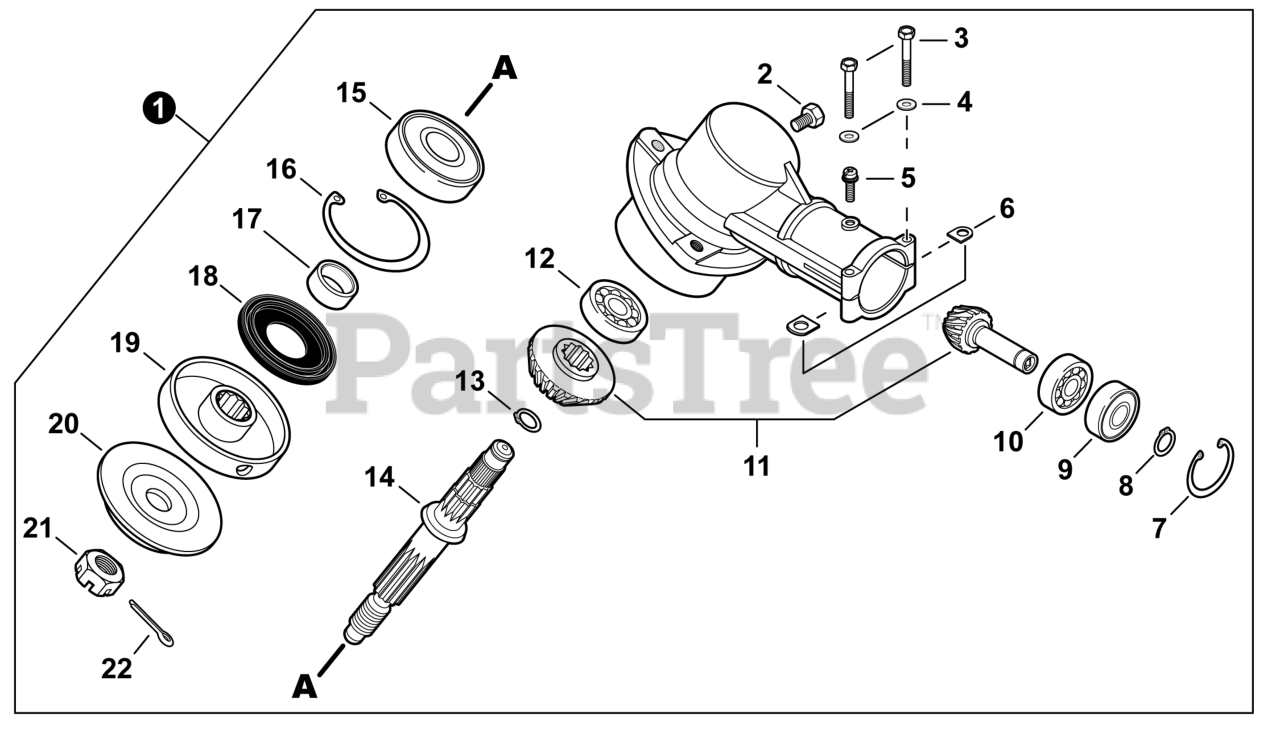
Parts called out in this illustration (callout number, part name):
1	GEAR CASE ASSY
2	BOLT M8×8
3	BOLT 5×35 SP
4	WASHER, FLAT 5.5×10×0.8
5	SCREW 5×10
6	D-WASHER
7	RING, SNAP Ø22
8	RING, SNAP Ø10
9	BEARING, BALL 6900Z
10	BEARING, BALL 6900
11	GEAR SET
12	BEARING, BALL 609
13	RING, SNAP Ø12
14	SHAFT, GEAR
15	BEARING, BALL 6201
16	RING, SNAP Ø32
17	SPACER 11.8×15×9
18	SEAL, OIL 22
19	PLATE, ADAPTOR - UPPER
20	PLATE, ADAPTOR - LOWER
21	NUT 10×1.25 LH
22	PIN, COTTER 2×22
